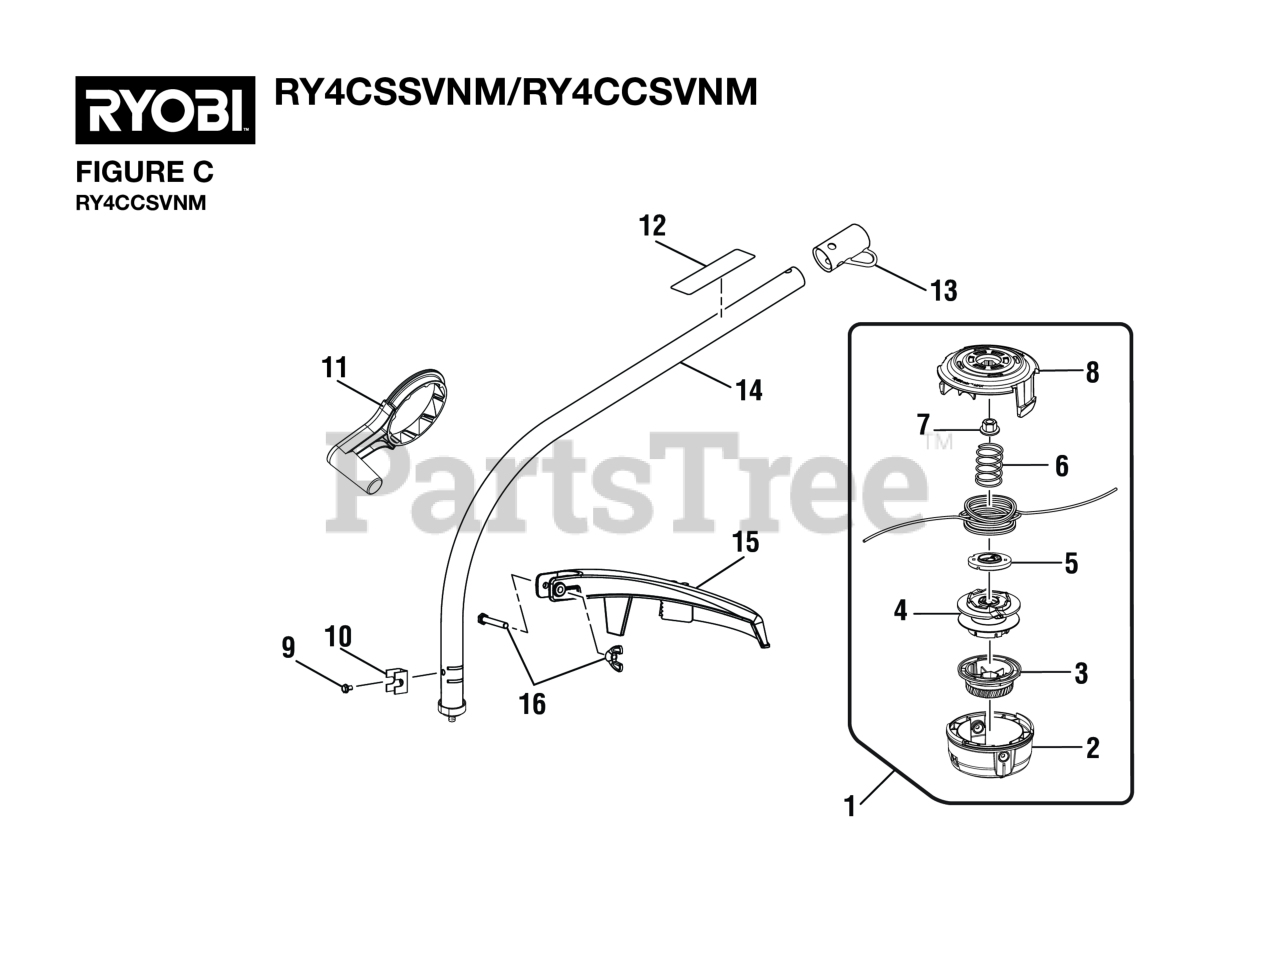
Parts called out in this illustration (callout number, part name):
1	Trimmer Head Assembly (.095)
2	Lower Housing
3	Bump Knob (Green)
4	Spool Assembly
5	String Guide
6	Compression Spring
7	Flange Nut (M8)
8	Upper Housing
9	Screw (#10-32 x 3/8 in., Hex Washer Hd. S.T.)
11	Crank Handle
12	Warning Icon Label
13	Hanger Cap
14	Curved Shaft Assembly (Inc. Key Nos. 9-12)
15	Grass Deflector Assembly
16	Fastener Parts Kit
